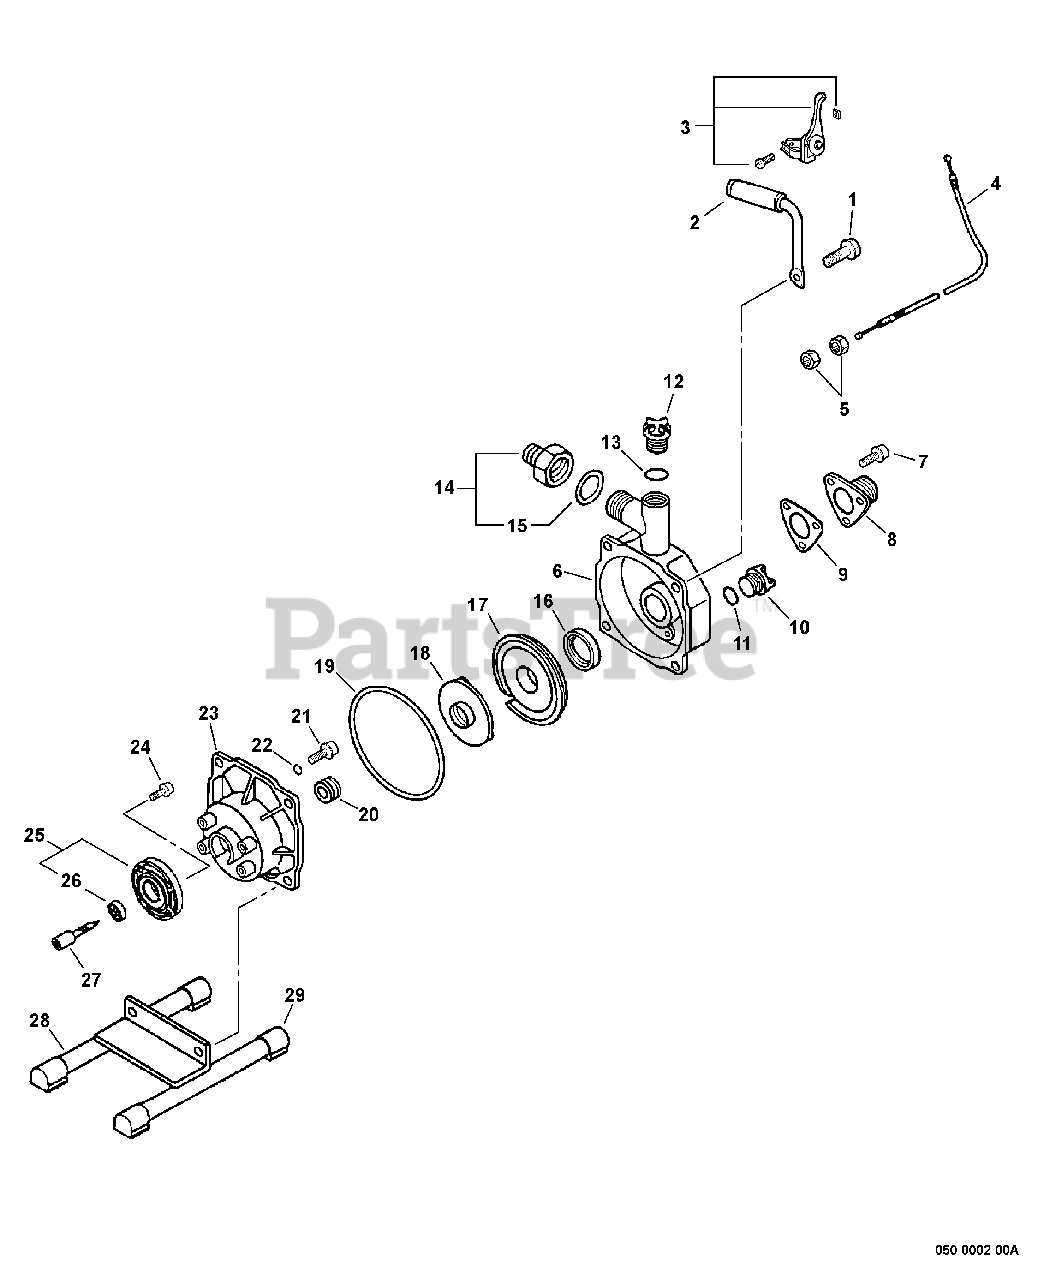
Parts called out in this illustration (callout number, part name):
1	BOLT TAPPING 8×35
3	CONTROL, THROTTLE
4	CABLE, THROTTLE
6	CASE, PUMP
7	BOLT - 6×20
8	CASE, CHECK VALVE
9	VALVE, CHECK
11	O-RING P-24
14	NIPPLE - 1×3/4"
17	CASE, IMPELLER
18	IMPELLER
20	SEAL, MECHANICAL
21	BOLT 5×25
23	CASE, PUMP
24	PUMP ADAPTOR ASSY
25	BEARING, BALL 6201
26	BOLT 5×25
27	SHAFT, PUMP
28	FRAME, PUMP
